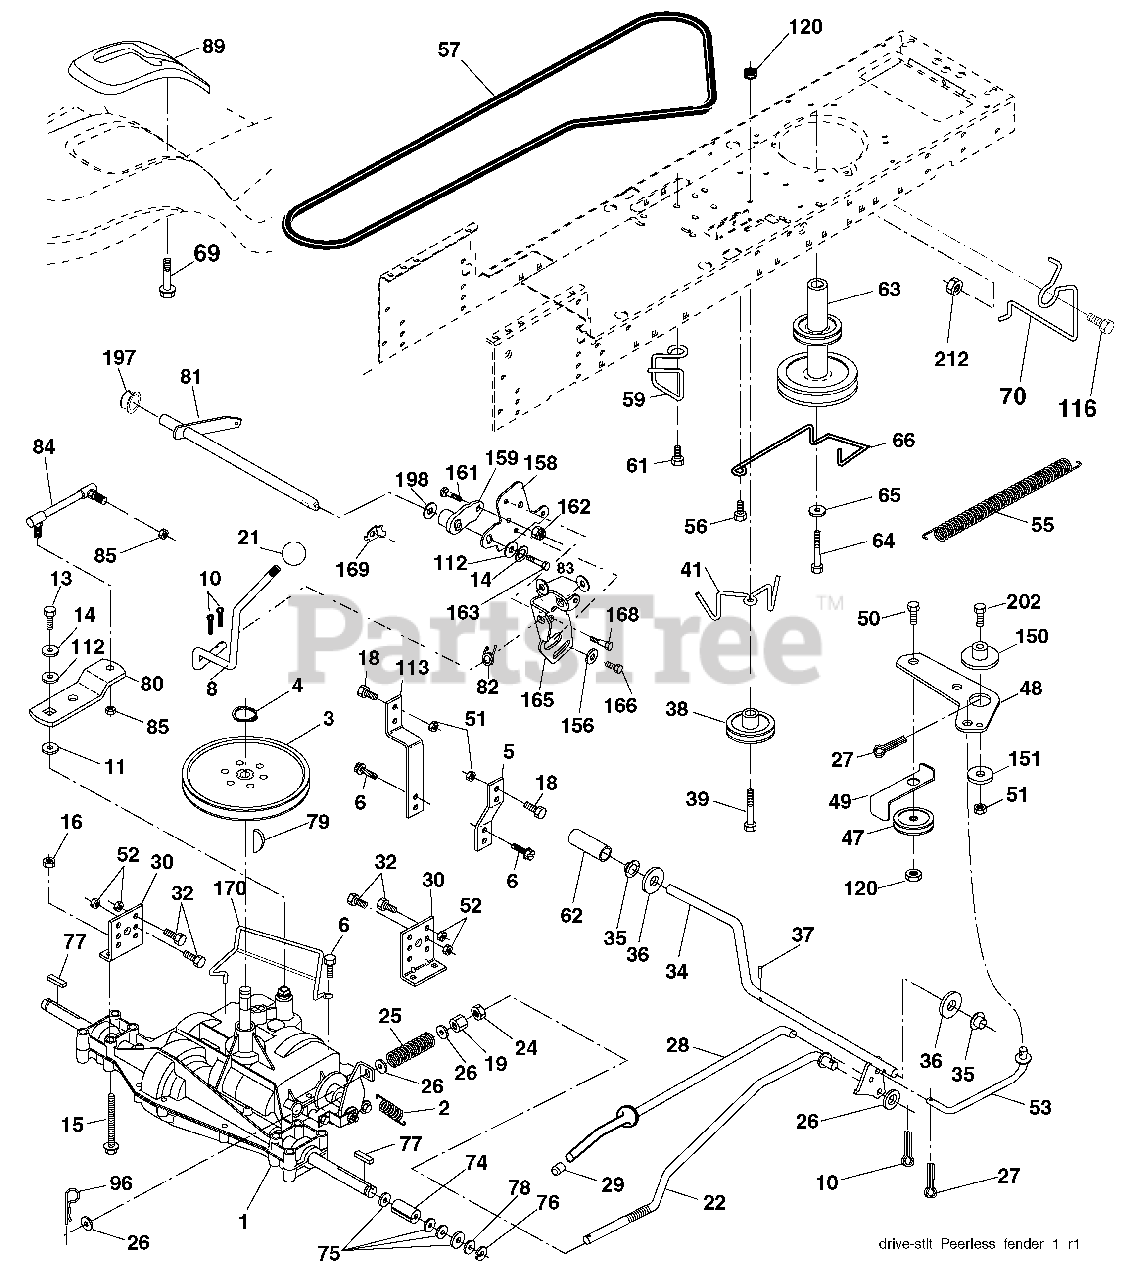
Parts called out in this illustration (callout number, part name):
2	Spring Return Brake T/a Zinc
3	Pulley Transaxle 18" tires
4	Ring Retainer # 5100-62
5	Strap Torque 30 Degrees
6	Screw 5/16-18 x 3/4
8	Rod Shift Fender Adjust Lt
10	Pin Cotter 1/8 x 1 Cad
11	Washer Plate Shf 388 Sq Hole
13	Bolt 1/4-28 unf Gr. 8 W/Patch
14	Washer Lock Hvy Helical
15	Bolt Hex FLGHD 5/16-18 Gr. 5
16	Nut Lock Hex w/ins 5/16-18
18	Bolt, Fin Hex 3/8-16 unc x 1 Gr. 5
19	Nut Lock 3/8-16 unc
21	Knob
22	Rod Brake Blk Zinc 26 840
24	Nut Hex Jam 3/8-16 unc
25	Spring Rod Brake 2 00 Zinc
26	Washer 13/32 x 13/16 x 16 Ga.
27	Pin Cotter 1/8 x 3/4 Cad
28	Rod Brake Parking LT/YT
29	Cap Brake Parking
30	Bracket Mtg Transaxle
32	Bolt Hex Hd 5/16-18 unc x 3/4
34	Shaft Asm Pedal Foot
35	Bearing Nylon Blk 629 Id
36	Washer 21/32 x 1 x 16 Ga.
37	Pin Roll 3/16 x 1"
38	Pulley Composite Flat
39	Bolt RDHD 3/8-16 unc x 2-3/4 Gr. 5
41	Keeper Belt Flat Idler
47	Pulley Idler V Groove Plastic
48	Bellcrank Asm
49	Retainer Belt Style Spring
50	Bolt Carr. Sh. 3/8-16 x 1-1/2 Gr. 5
51	Nut Crownlock 3/8-16 unc
52	Nut Crownlock 5/16-18 unc
53	Link Clutch
55	Spring Return Clutch 6 75
56	Screw 3/8-16 x 1-1/4
57	V-Belt Ground Drive
59	Keeper Belt Span Ctr
61	Screw 3/8-16 x .875
62	Cover Pedal Blk Round
63	Engine Pulley
64	Bolt Hex
65	Washer Lock Hvy Hlcl Spr 7/16
66	Keeper Belt Engine Foolproof
69	Screw Hex wsh HiLo 1/4 x 1/2 unc
70	Guide Belt Mower Drive RH
74	Spacer Axle
75	Washer 25/32 x 1 1/4 x 16 Ga.
76	E-ring #5133-75
77	Key Square 2 0 x 1845/ 1865
78	Washer 25/32 x 1-5/8 x 16 Ga.
79	Key Woodruff #9 3/16 x 3/4
80	Arm Shift
81	Shaft Asm Cross Tapered PMST/20
82	Spring Torsion T/a
83	Washer 17/32 x 3/4 x 16 Ga.
84	Link Transaxle Dana/18" Zinc
85	Nut Lock Center 1/4 - 28 FNTHD
89	Console Shift STLT
96	Retainer Spring 1"
112	Washer 9/32 x 3/4 x 10 Ga.
113	Strap Torque LT
116	Bolt Rdhd Sq Neck 3/8-16 x 1
120	Nut Lock Flg. 3/8-16 unc
150	Spacer Retainer
151	Washer 13/32 x 2 x 10
156	Washer Srrted 5/16ID x 1.125
158	Bracket Shift Mount
159	Hub Tapered Flange Shift Lt
161	Bolt Rdhd Sqnk 1/4-20 x 3/4
162	Nut Crownlock 1/4-20 unc
163	Bolt Hex Fin 1/4-20 unc x 1 Gr. 5
165	Bracket Pivot Lever
166	Screw 5/16-18 x 5/8
168	Bolt Shoulder 5/16-18 x .561
169	Plate Fastening
170	Keeper Belt Transaxle Gear
197	Nyliner Snap-In
198	Washer Nyliner
202	Bolt RdHd 3/8-16 unc x 1-3/4 Gr. 5
212	Nut Hexflange Lock
